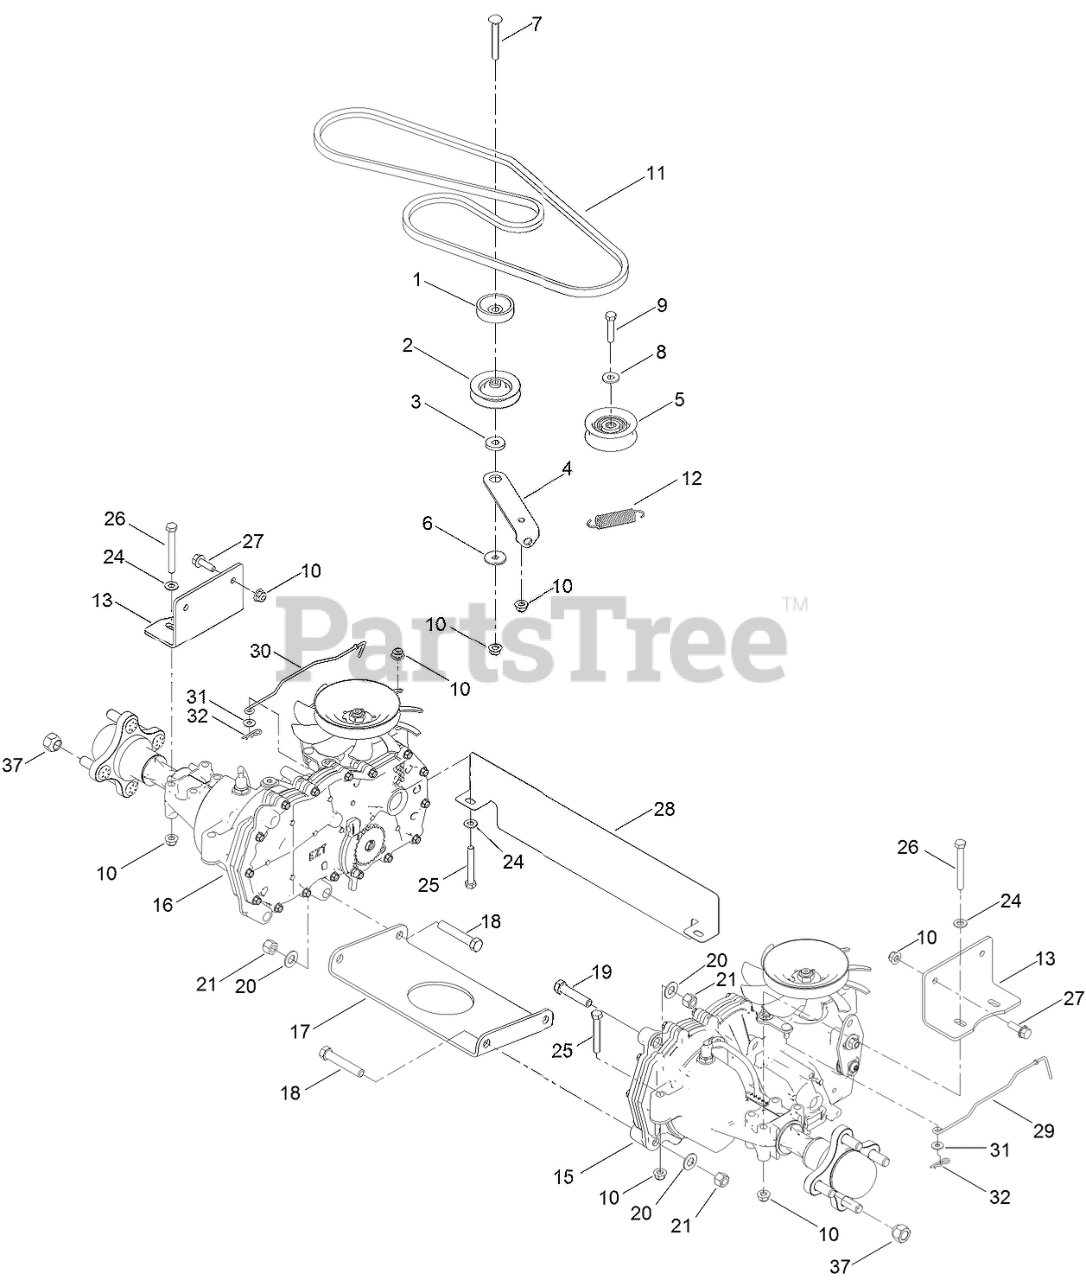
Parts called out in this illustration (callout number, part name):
1	SPACER
2	PULLEY-IDLER
3	SPACER-IDLER ARM
4	ARM-IDLER
5	PULLEY-IDLER, FLAT
6	WASHER-PIVOT
7	SCREW-CARR
8	WASHER-FLAT
9	SCREW-HH
10	NUT-HF
11	V-BELT
12	SPRING-PEDAL, RETURN
13	MOUNT-HYDRO
15	LH HYDRO TRANSAXLE ASM
16	RH HYDRO TRANSAXLE ASM
17	PLATE-CROSS, HYDRO
18	SCREW-HH
19	SCREW-HH
20	WASHER-FLAT
21	NUT-HEX
24	WASHER-PLAIN
25	SCREW-HH
26	SCREW-HH
27	SCREW-HHF
28	GUARD REAR, WIDE
29	ROD-BYPASS, LH
30	ROD-BYPASS, RH
31	WASHER
32	PIN-HAIR
37	NUT-LUG
